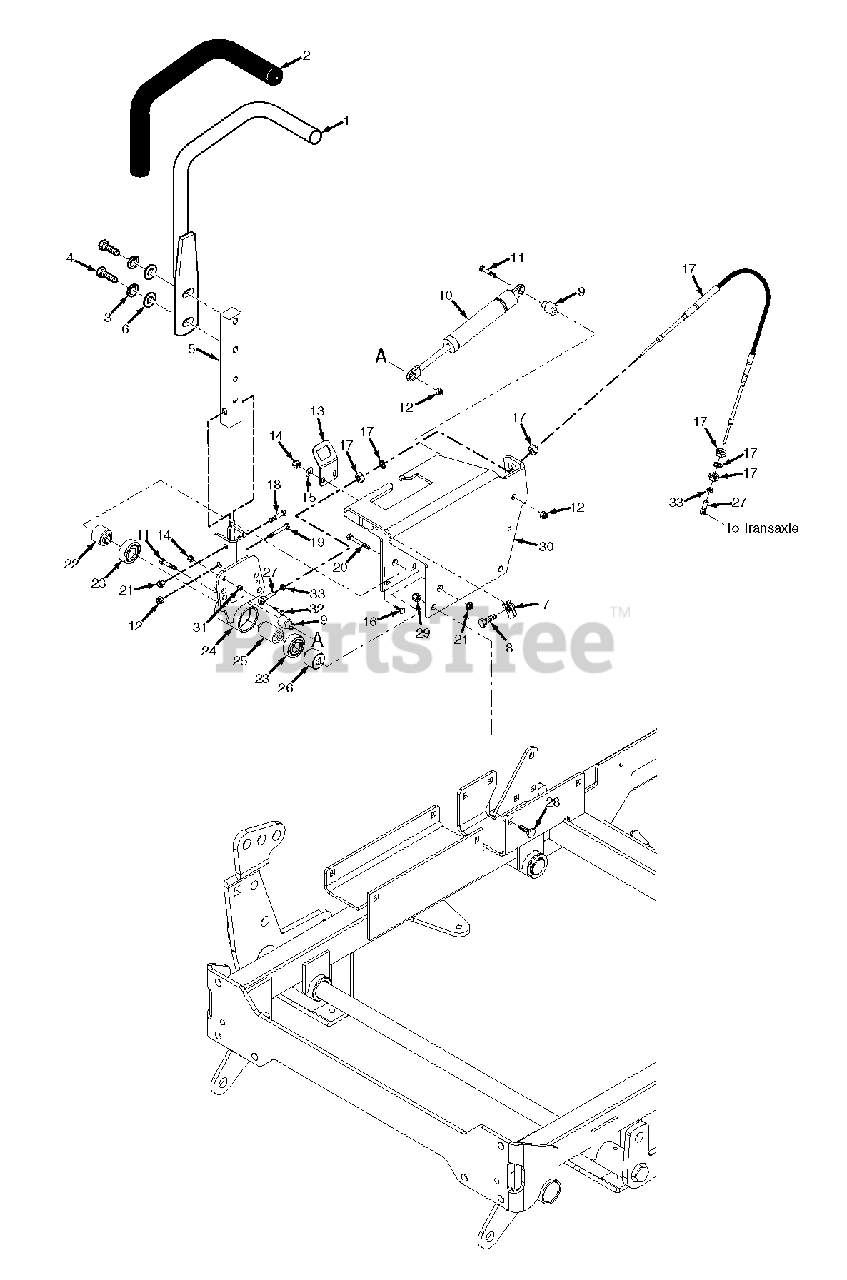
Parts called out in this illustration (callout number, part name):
1	Handle Bar w/Grip
2	Grip, Control Handle
3	Lockwasher, 3/8" Spring
4	Bolt, Hex Head 3/8-16 x 1-1/4'
5	Bar, Control Lever
6	Flatwasher, 3/8-.391 x .938 x .105
7	U-Nut, 3/8-16
8	Bolt, Hex Head 3/8-16 x 2" Special
9	Spacer
10	Damper
11	Bolt, Hex Head 5/16-18 x 1-1/2"
12	Nut, Elastic Stop 5/16-18
13	Bracket, Operator Presence Switch
14	Nut, Elastic Stop 1/4-20
15	Flatwasher, 1/4-.312 x .750 x .065
16	Bolt, Carriage 1/4-20 x 3/4"
17	Control Cable, Hydro
18	Bolt, Hex Head 3/8-16 x 2"
19	Bolt, Hex Head 5/16-18 x 2"
20	Bolt, Hex Head 3/8-16 x 4-1/2"
21	Nut, Elastic Stop 3/8-16
22	Spacer, Controls
23	Bearing
24	Pivot Weldment, Control Arm LH
24	Pivot Weldment, Control Arm RH
25	Spacer, Bearing
26	Spacer, Controls
27	Rod End, 1/4-28 RH Thread
28	Bolt,Carriage 5/16-18 x 1"
29	Nut, Serrated Flange 5/16-18
30	Bracket Weldment, Control Lever RH w/Decal
30	Bracket Weldment, Control Lever LH w/Decal
31	Spacer
32	Bolt, Hex Head 1/4-20 x 1-1/4"
33	Nut, Jam 1/4-28 UNF
